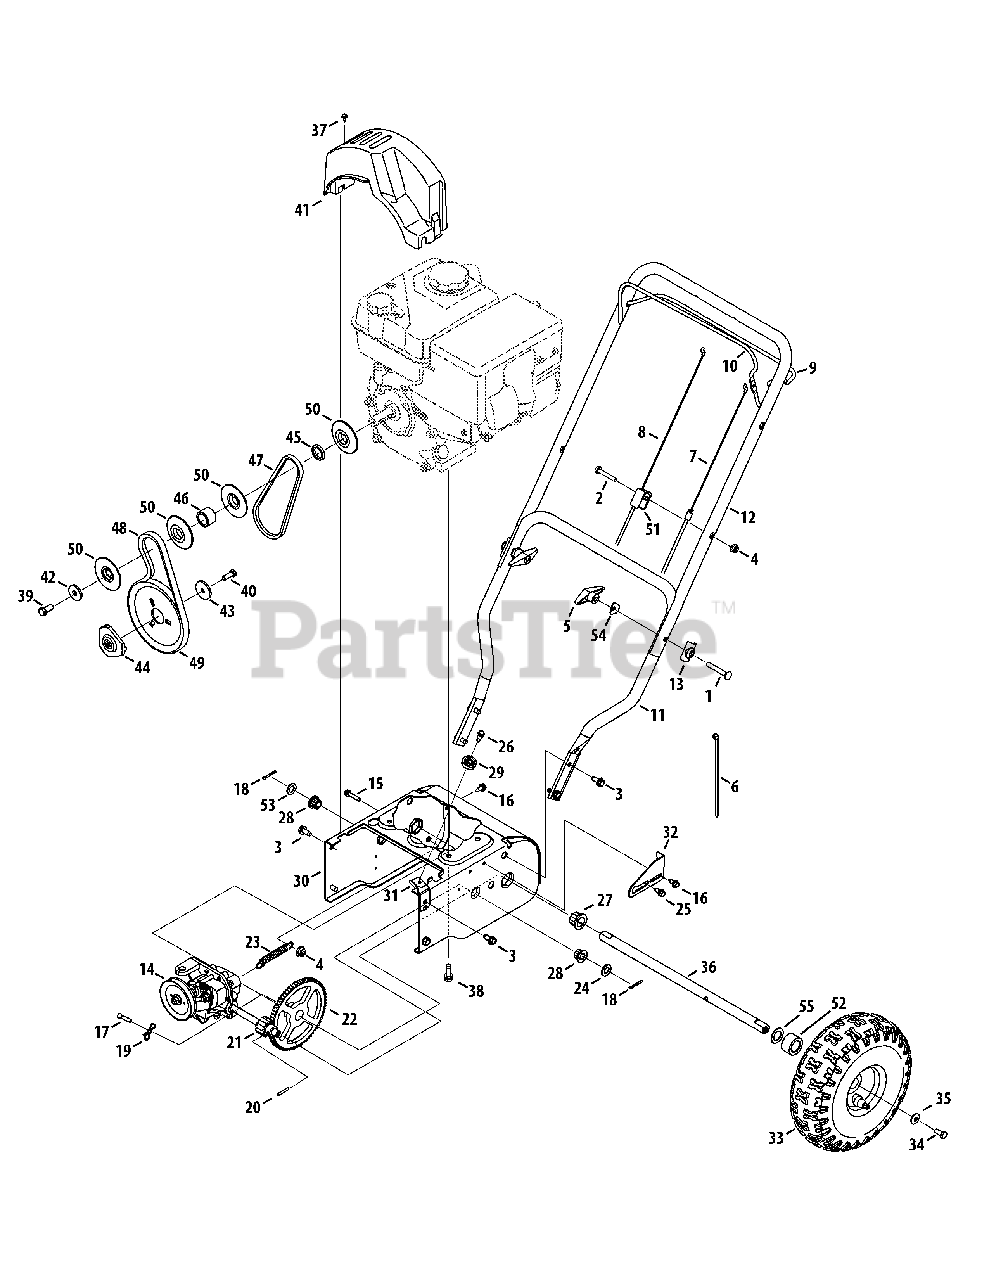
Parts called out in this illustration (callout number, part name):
1	Carriage Screw, 5/16-18 x 2.25
2	Mach. Screw, 1/4-20 x 1.50
3	Screw, 5/16-18 x .75
4	Flange Lock Nut, 1/4-20
5	Wing Knob, 5/16-18
6	Cable Tie
7	Drive Cable
8	Auger Cable
9	Drive Control
10	Auger Control
11	Lower Handle
12	Upper Handle
13	Handle Tab
14	Transmission Assembly
15	Self-Tapping Screw, 1/4-20 x 1.25
16	Screw 1/4-20 x .625
17	Clevis Pin
18	Cotter Pin, 1/8 x 1.0
19	Bow Tie Cotter Pin, 72
20	Roll Pin
21	Pinion, 14T
22	Gear, 70T
23	Extension Spring
24	Flat Washer
25	Shoulder Screw, 1/4-20
26	Shoulder Screw, 1/4-28
27	Hex Flange Bearing
28	Hex Flange Bearing
29	Cable Roller
31	Auger Cable Bracket
33	Wheel Assy. ,Snow Hog, Gray
34	Lock Bolt, 5/16-24 x .75
35	Bell Washer, .34 x .872 x .06
37	Hex Screw, #10-16 x .500
38	Sems Screw, 3/8-16 x 1.0
39	Hex Bolt ,3/8-24 x .875
40	Lock Bolt, 5/16-24 x .875
41	Belt Cover
42	Flat Washer, .406 ID x 1.25 OD
43	Flat Washer, .34 ID x 1.50 OD
44	Pulley: Adapter ,.75 Dia.
45	Flat Washer, .876 x 1.25 x .11
46	Spacer, .876 x 1.25 x .94
47	V-belt, 3/8 x 21.108 Lg.
48	V-belt, 3/8 x 26.375 Lg.
49	Auger Pulley
50	Pulley Half
51	Cable Clip
53	Flat Washer, .53 x .93 x .05
54	Saddle Washer
55	Flat Washer, .793 x 1.24 x .06
